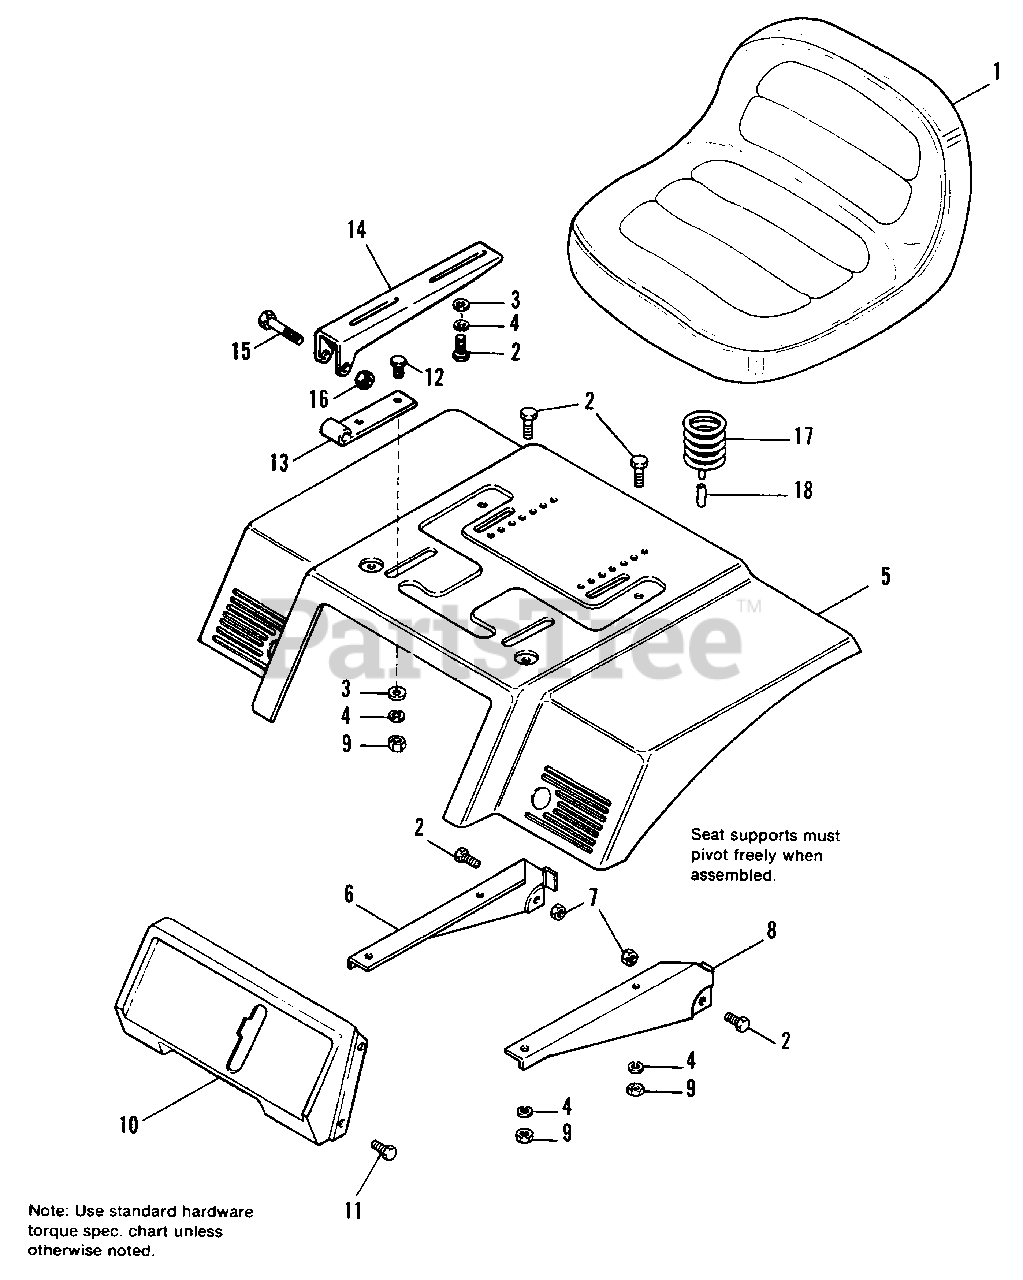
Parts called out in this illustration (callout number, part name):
2	CAPSCREW, 5/16-18 x 3/4
3	WASHER, 5/16
4	LOCKWASHER, 5/16
5	DECK, Seat
6	SUPPORT, Seat, R.H.
7	NUT, Hex, 5/16-18
8	SUPPORT, Seat. L.H.
9	NUT, Hex, 5/16-18
10	PANEL, Shift
11	SCREW, Taptite, 1/4-20 x 1/2
12	CAPSCREW, Hex, 5/16-18 x 1
13	HINGE, Lower
14	HINGE, Upper
15	CAPSCREW, Hex Hd., 3/8-16 x 2
16	NUT, Hex Lock, 3/8-16
17	SPRING, Seat
18	COVER, Wire
